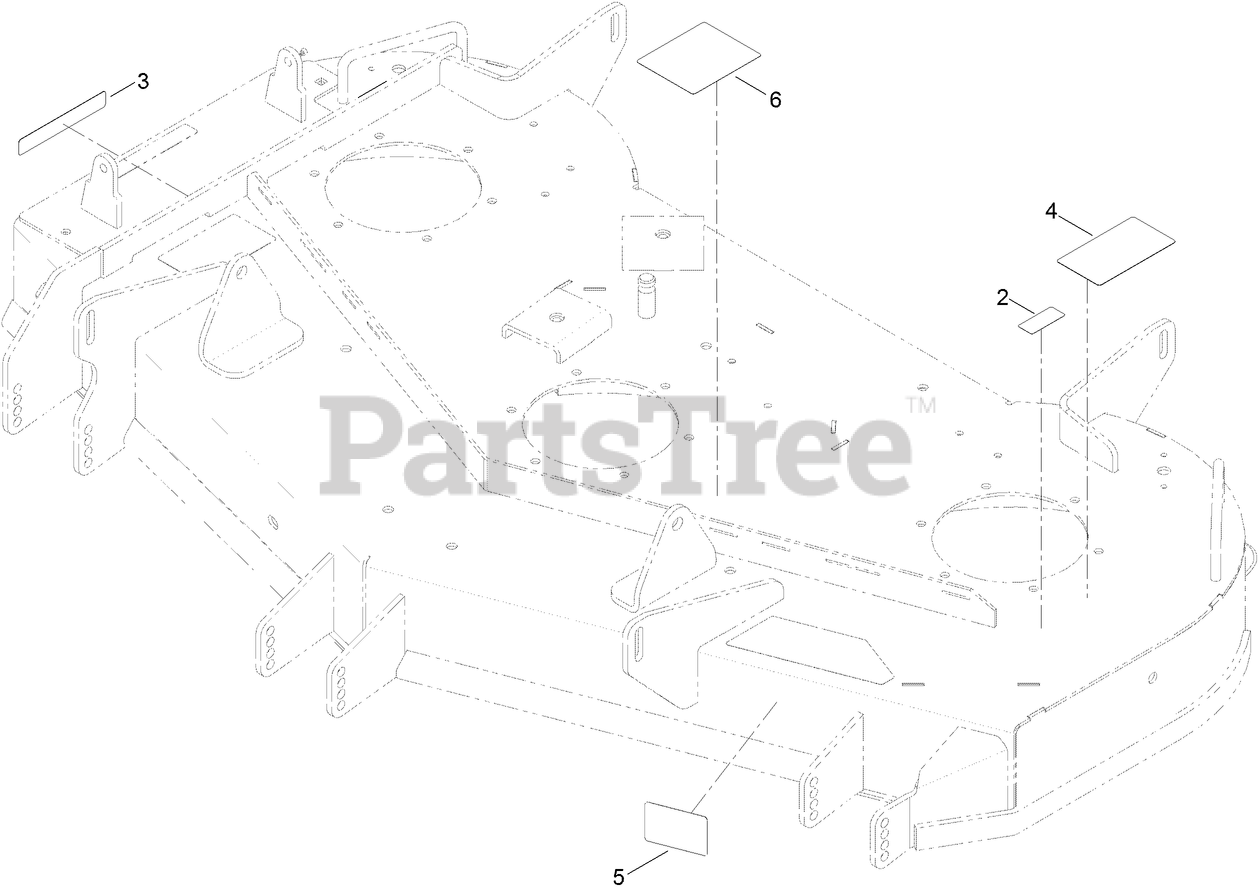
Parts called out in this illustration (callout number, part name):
2	DECAL-DANGER
3	DECAL-DANGER
4	DECAL-DANGER
5	DECAL-SCALP, ANTI
6	DECAL-ROUTING, BELT
